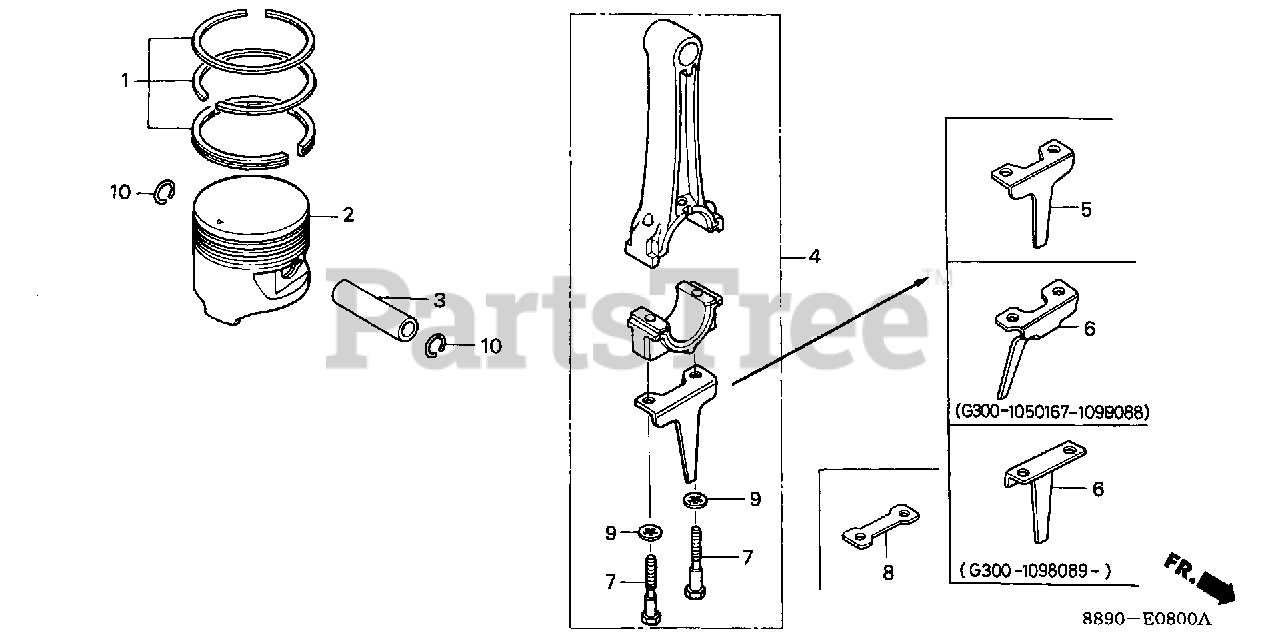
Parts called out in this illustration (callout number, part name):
1	RING SET, PISTON (STD)
1	RING SET, PISTON (0.25)
1	RING SET, PISTON (0.50)
1	RING SET, PISTON (0.50) (TEIKOKU)
1	RING SET, PISTON (0.75)
2	PISTON (STD)
2	PISTON (0.25)
2	PISTON (0.50)
2	PISTON (0.75)
3	PIN, PISTON
4	ROD ASSY., CONNECTING
4	ROD ASSY., CONNECTING (UNDER SIZE)
5	DIPPER, CONNECTING ROD (NOT AVAILABLE)
6	DIPPER, CONNECTING ROD
7	BOLT, CONNECTING ROD (7MM)
7	BOLT, CONNECTING ROD (7MM) (NOT AVAILABLE)
8	WASHER, LOCK (7MM)
9	WASHER, LOCK (7MM)
10	CLIP, PISTON PIN (16MM)
